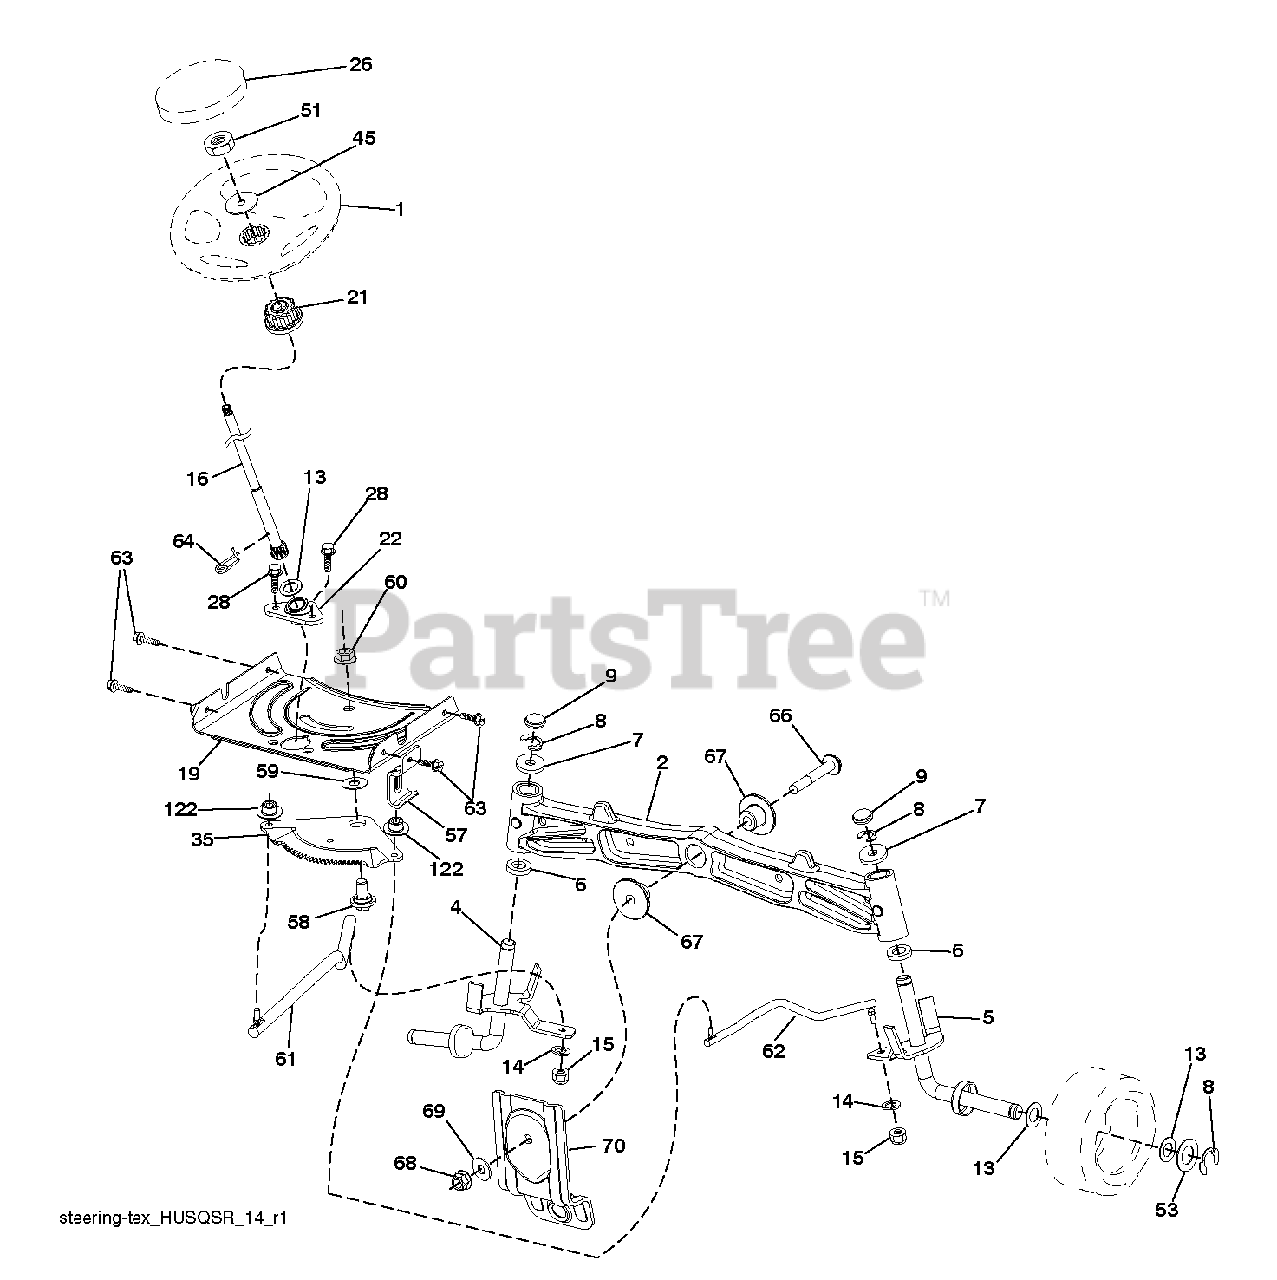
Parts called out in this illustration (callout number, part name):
1	WHEEL.STEER.HUSQ.SR.498.OVMLD
2	AXLE.CAST.IRON
4	SPINDLE.WELDED.LH.15"TEX
5	SPINDLE.WELDED.RH.15"T
6	THRUST WASHER
9	CAP.SPINDLE.BLACK
14	WASHER, LOCK 3/8
15	NUT CROWNLOCK 3/8-24
16	SHAFT, STEERING
19	PLATE.STEER.DDL.NLT/NG
21	ADAPTER, WHEEL STNG..
22	STEERING.SUPT.LOWER.
26	INSERT.CAP.WHL.STRG.HUSQ.PREM
28	SCREW, 3/8-16X3/4
35	GEAR.SECTOR.PLATE.DDL.
45	WASHER 9/16"ID, 2 3/8"OD
51	NUT.HEX.1/2-20
53	WASHER.HARDENED
57	BRKT.UPSTOP.GT/LT.TEX
58	BOLT.SHOULDER.SECTOR.P
59	WASHER.THURST.SECTOR.S
60	NUT FLANGE LOCK 5/8-11
61	DRAGLINK.LH.BALLSTUD.D
62	DRAGLINK.RH.BALLSTUD.D
63	SCREW
64	RETAINER.CLIP.SPRING.S
66	BOLT HEX FGHD 7/16-14 X 3 SERR
67	BUSHING.PM.FRONT AXLE
68	NUT.LOCK.FLANGE.7/16
69	WASHER.1.5X.505X.118
70	BRKT.DECK.SUSPENSION.F
122	CAP.GEAR.SECTOR.TEX
